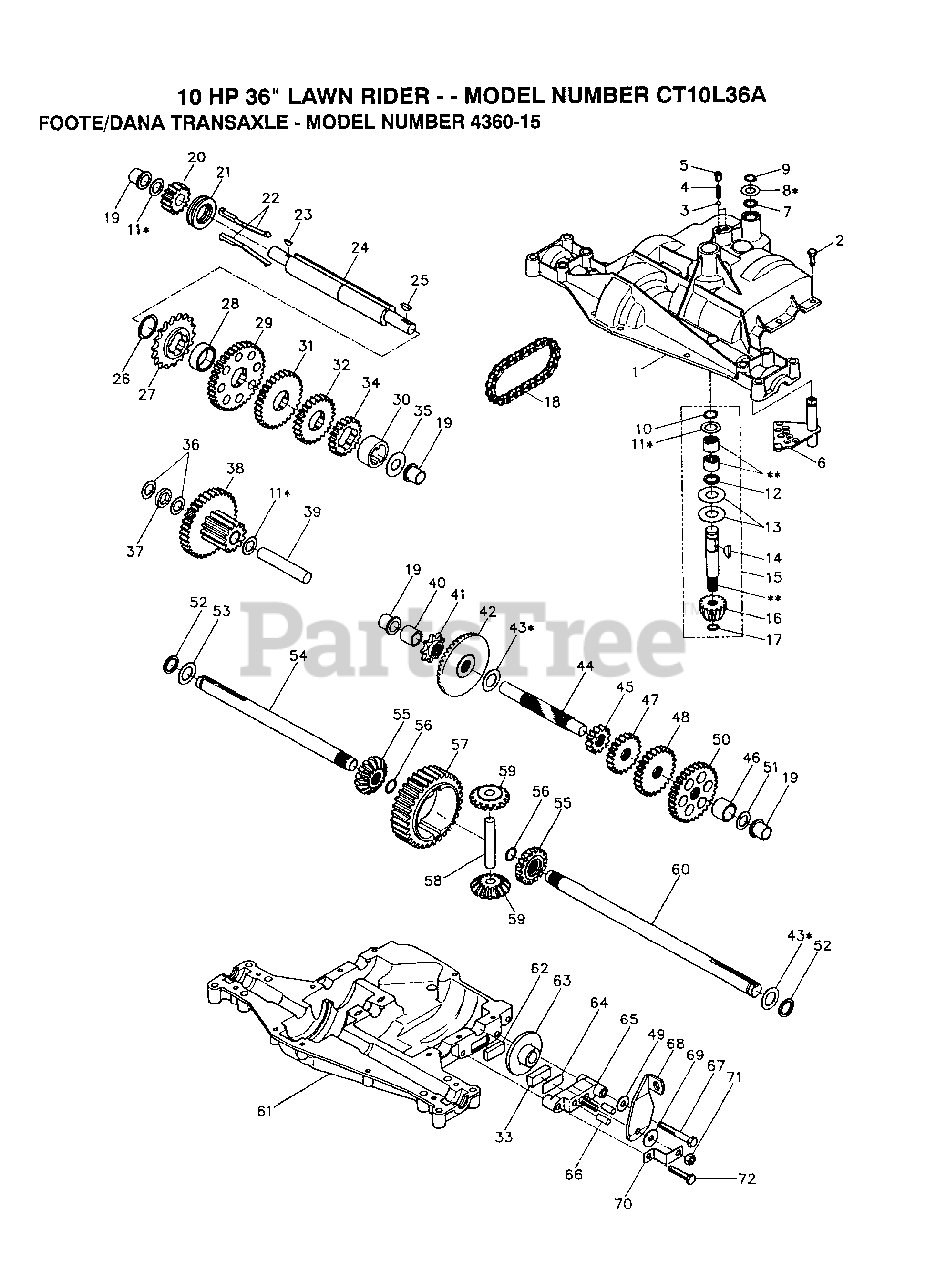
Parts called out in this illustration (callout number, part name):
3	"DETENT, BALL(68003)"
4	"SPRING, DETENT LT"
5	"SCREW, SET LT"
7	ORING T
9	RETAINING RING LT
10	RETAINING RING LT
11	WASHER
12	O-RING T
13	WASHER T
14	WOODRUFF KEY
15	IMPUT KIT T
16	PINION 14T T
17	"RING,RETAINING LT"
18	"CHAIN,24 PTCH LT"
19	BEARING.FLNG.5510
22	KEY T
25	WOODRUFF KEY
26	"RING,RETAINING LT"
27	SPROCKET 18T T
28	SPACER YT
29	KIT.GEAR.12/37TH
32	GEAR 25T LT
33	PUCK T
35	"WASHER, PLAIN LT"
36	WASHER 025
37	SPACER
38	ASSM GEAR COMB
39	SHAFT IDLER T
40	SPACER T
41	SPROCKET 9T LT
43	WASHER LT
44	SHAFT T
48	"GEAR, SPUR 25T LT"
49	WASHER T
50	"GEAR, SPUR 31T LT"
51	WASHER 060
53	WASHER 062
55	GEAR 15T T
56	"RING,RETAINING LT"
58	SHAFT T
59	GEAR 1ST T
62	PUCK T
63	BRAKE DISC. T
64	SPACER LT
66	PIN T
67	SCREW T
68	LEVER ACTUATOR
69	WASHER LT
71	NUT.LOCK.5/16-24
72	"SCREW, TAPPING LT"
